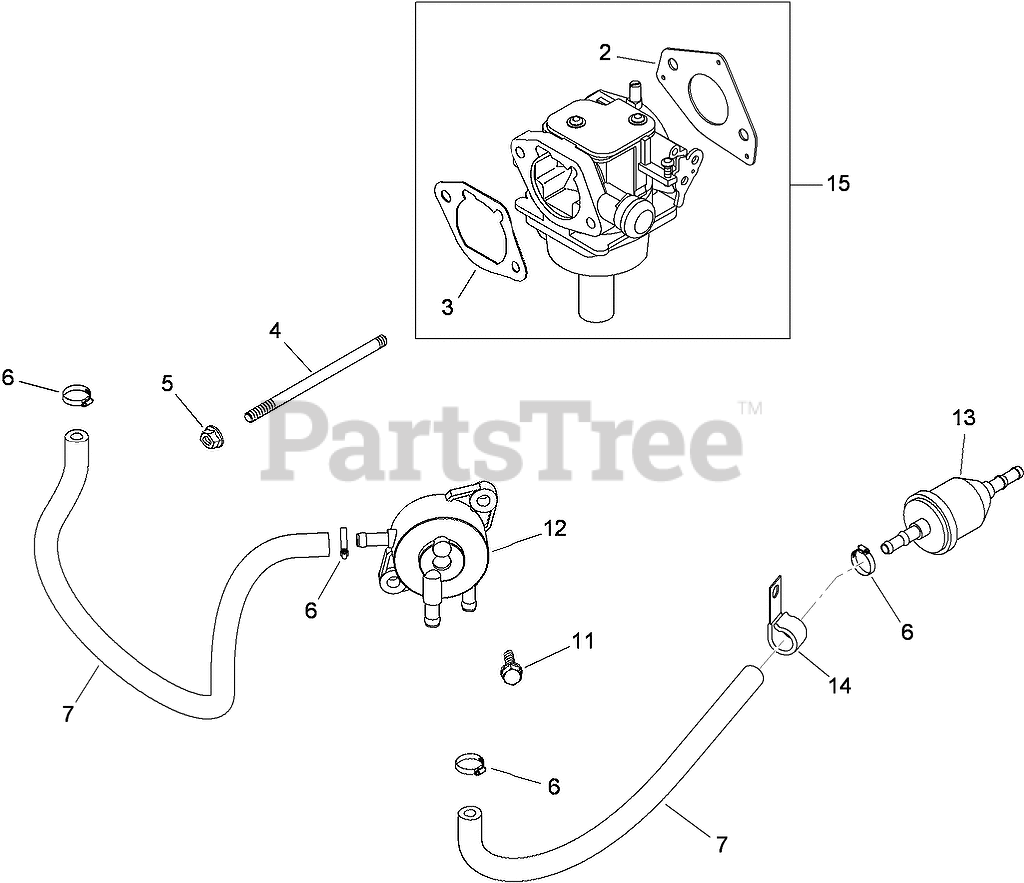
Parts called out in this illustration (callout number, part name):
2	GASKET-CARBURETOR
3	GASKET-BASE, AIR CLEANER
4	STUD (M6X1.0X106)
5	NUT-FLANGE (M6X1.0)
6	CLAMP-HOSE, SPRING (1/2)
7	LINE-FUEL (24.0 CUT TO LENGTH)
11	SCREW-TAP (M6X1.7X18)
12	PUMP-FUEL
13	FILTER-FUEL
14	CLIP-CABLE
15	CARBURETOR KIT-19mm KEIHIN (INCLUDES 2, 3)
